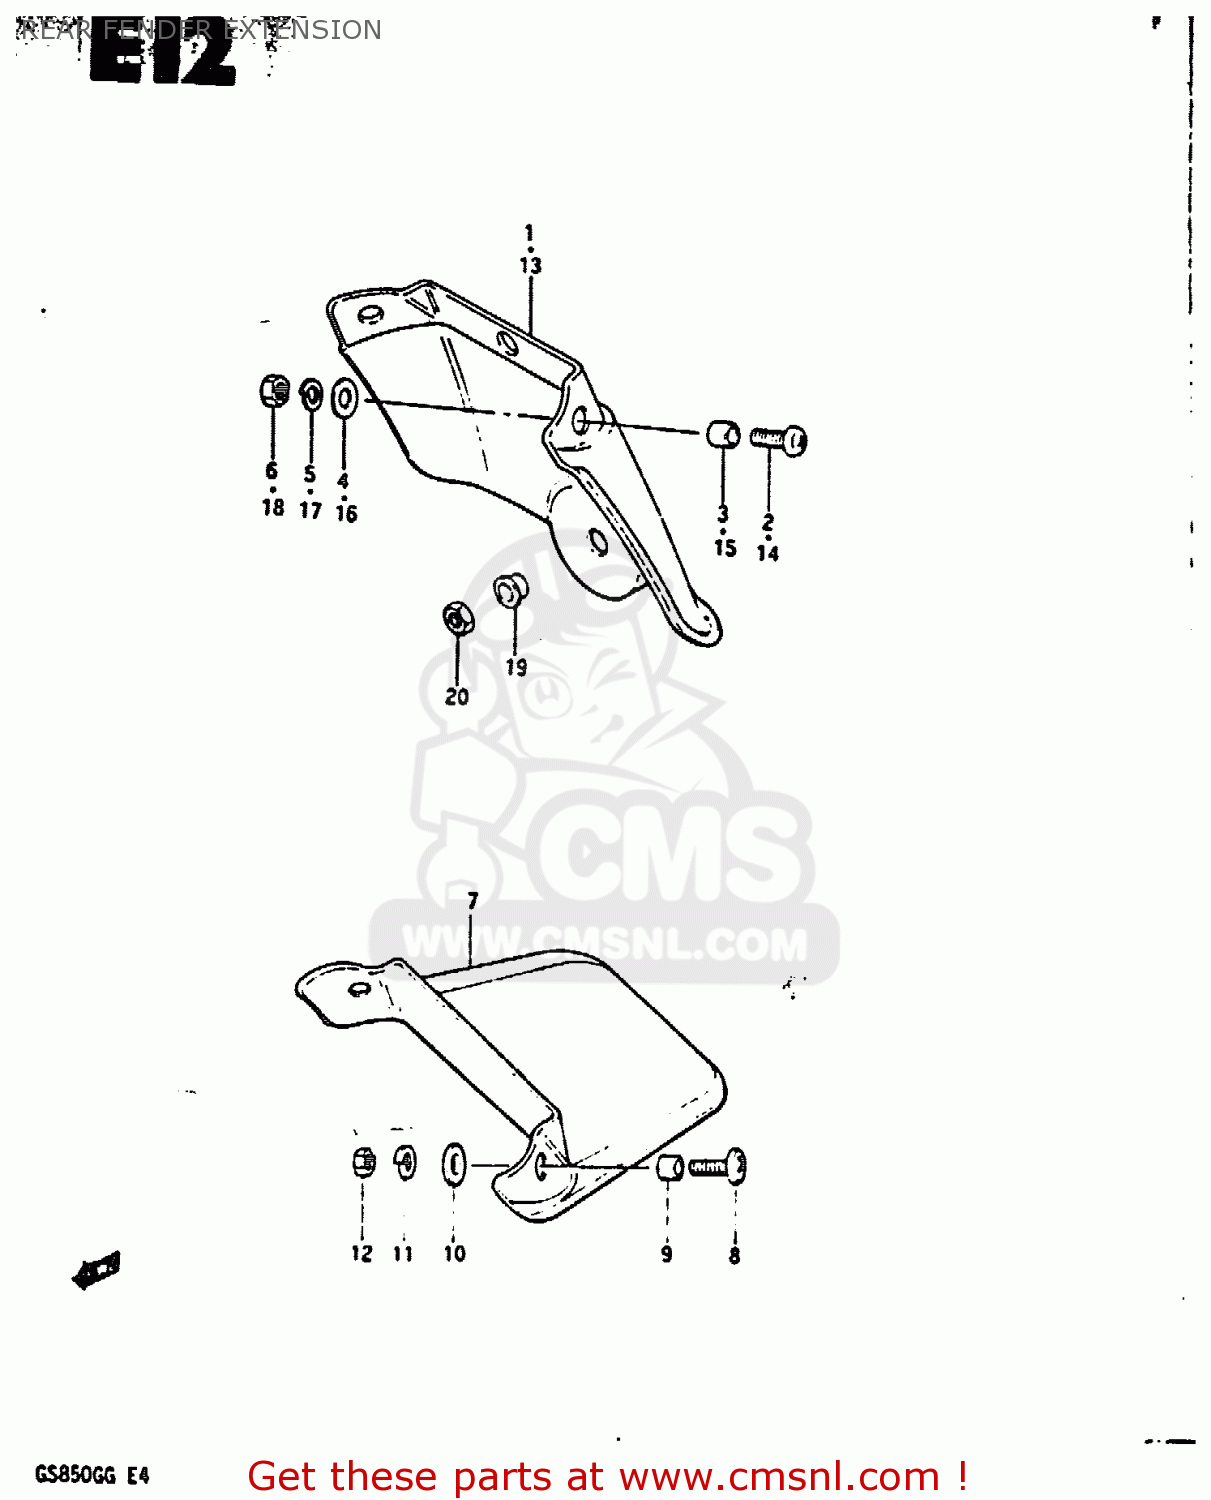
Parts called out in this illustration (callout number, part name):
1	EXTENSION,REAR FENDER
2	SCREW (6X15)
3	SPACER(6.2X8.3X5.7)
4	WASHER(6.5X18X1)
5	WASHER,LOCK
6	NUT
7	EXTENSION,REAR FENDER
8	SCREW (6X15)
9	SPACER(6.2X8.3X5.7)
10	WASHER(6.5X18X1)
11	WASHER,LOCK
12	NUT
13	EXTENSION,REAR FENDER
14	SCREW (6X15)
15	SPACER(6.2X8.3X5.7)
16	WASHER(6.5X18X1)
17	WASHER,LOCK
18	NUT
19	SPACER
20	NUT
